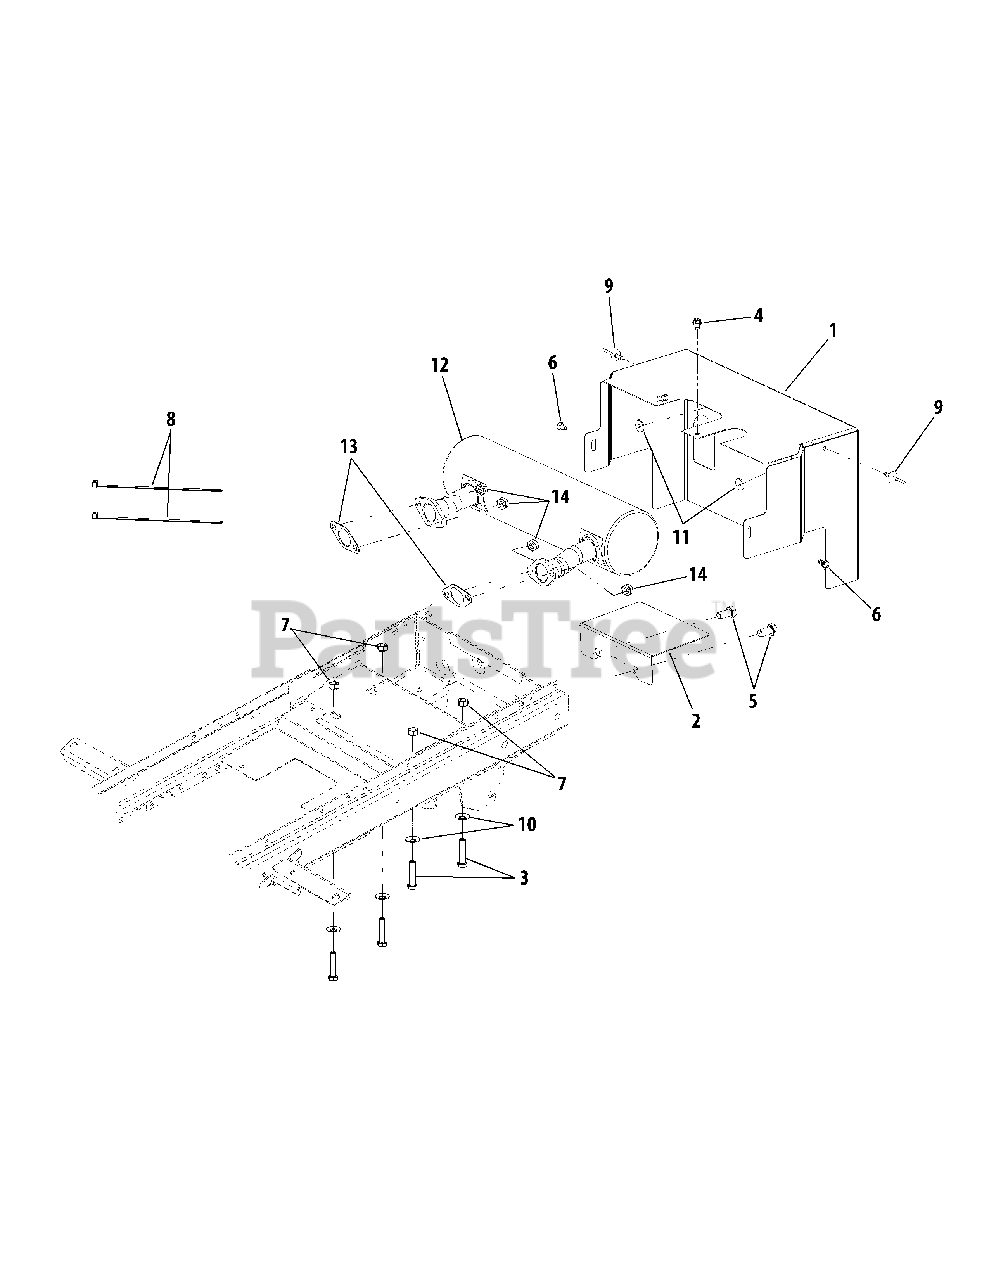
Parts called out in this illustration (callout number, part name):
1	Shield, Heat
2	Shield, Clutch
3	Bolt, Eng Mount, 3/8-24 x 1.75 GR5
4	Screw, Hx Wsh Hd Tapp, 1/4-20 x .375
5	Screw, Hx Cap Lock, 3/8-16 x .75 Gr5
6	Screw, Hex Cap, M6 x 1 x 10
7	Nut, Hex Lock, 3/8-24
8	Tie, Cable
9	Rivet, Pop, 3/16 x .45
10	Washer, Bell, .380 x .88 x .062
11	Washer, Flat, .194 x .62 x .063
12	Muffl er Assembly
13	Gasket, Exhaust
14	Nut, Hex Flange
